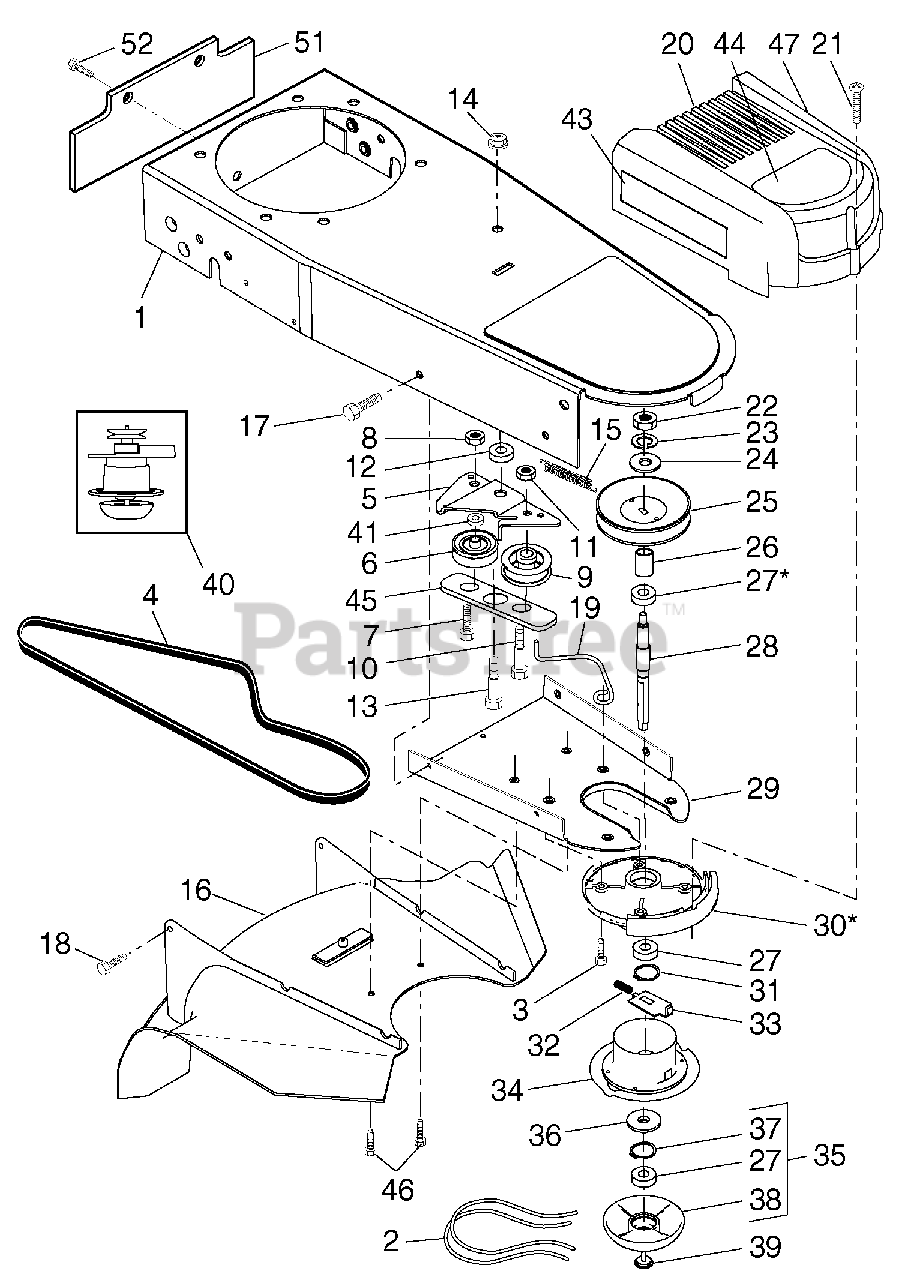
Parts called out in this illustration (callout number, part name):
1	Chassis Assembly
2	Line, Trimmer .155 diameter x 18.75 long
3	Screw, Self-Tapping 5/16-18 x 1
4	V-Belt
5	Bracket, Idler
6	Pulley, Idler, V-Groove
7	Bolt, Hex Head 3/8-16 x 1.25
8	Locknut, Hex 3/8-16
9	Pulley, Idler, Flat
10	Bolt, Shoulder
11	Locknut, Hex 5/16-18
12	Spacer
13	Bolt, Shoulder
14	Locknut, Flange
15	Spring, Return
16	Defl ector, Bottom
17	Screw 1/4-20 x 1/2
18	Screw #10-24 x 3/4
19	Belt Keeper
20	Cover, Chassis, Top
21	Screw #10-24 x 1-3/4
22	Nut, Hex 3/8-24 UNF
23	Washer, Lock 3/8
24	Washer, Flat 3/8
25	Pulley, Driven
26	Spacer, Pulley
27	Bearing
28	Jackshaft
29	Cover, Chassis, Bottom
30	Spindle Housing Assembly
31	Ring, Retaining, External, 17mm
32	Spring, Locking Plate
33	Locking Plate
34	Carrier Plate Assembly
35	Mow Ball Assembly
36	Cover, Bearing
37	Ring, Retaining, Internal, 40mm
38	Mow Ball
39	Bolt, Mow Ball
40	Spindle Assembly, Complete
41	Spacer
43	Decal, Instruction
44	Decal, Chassis Cover
45	Belt Keeper, Bottom
46	Screw, Self-Tapping
47	Decal, Instruction
51	Defl ector, Rear
52	Screw
